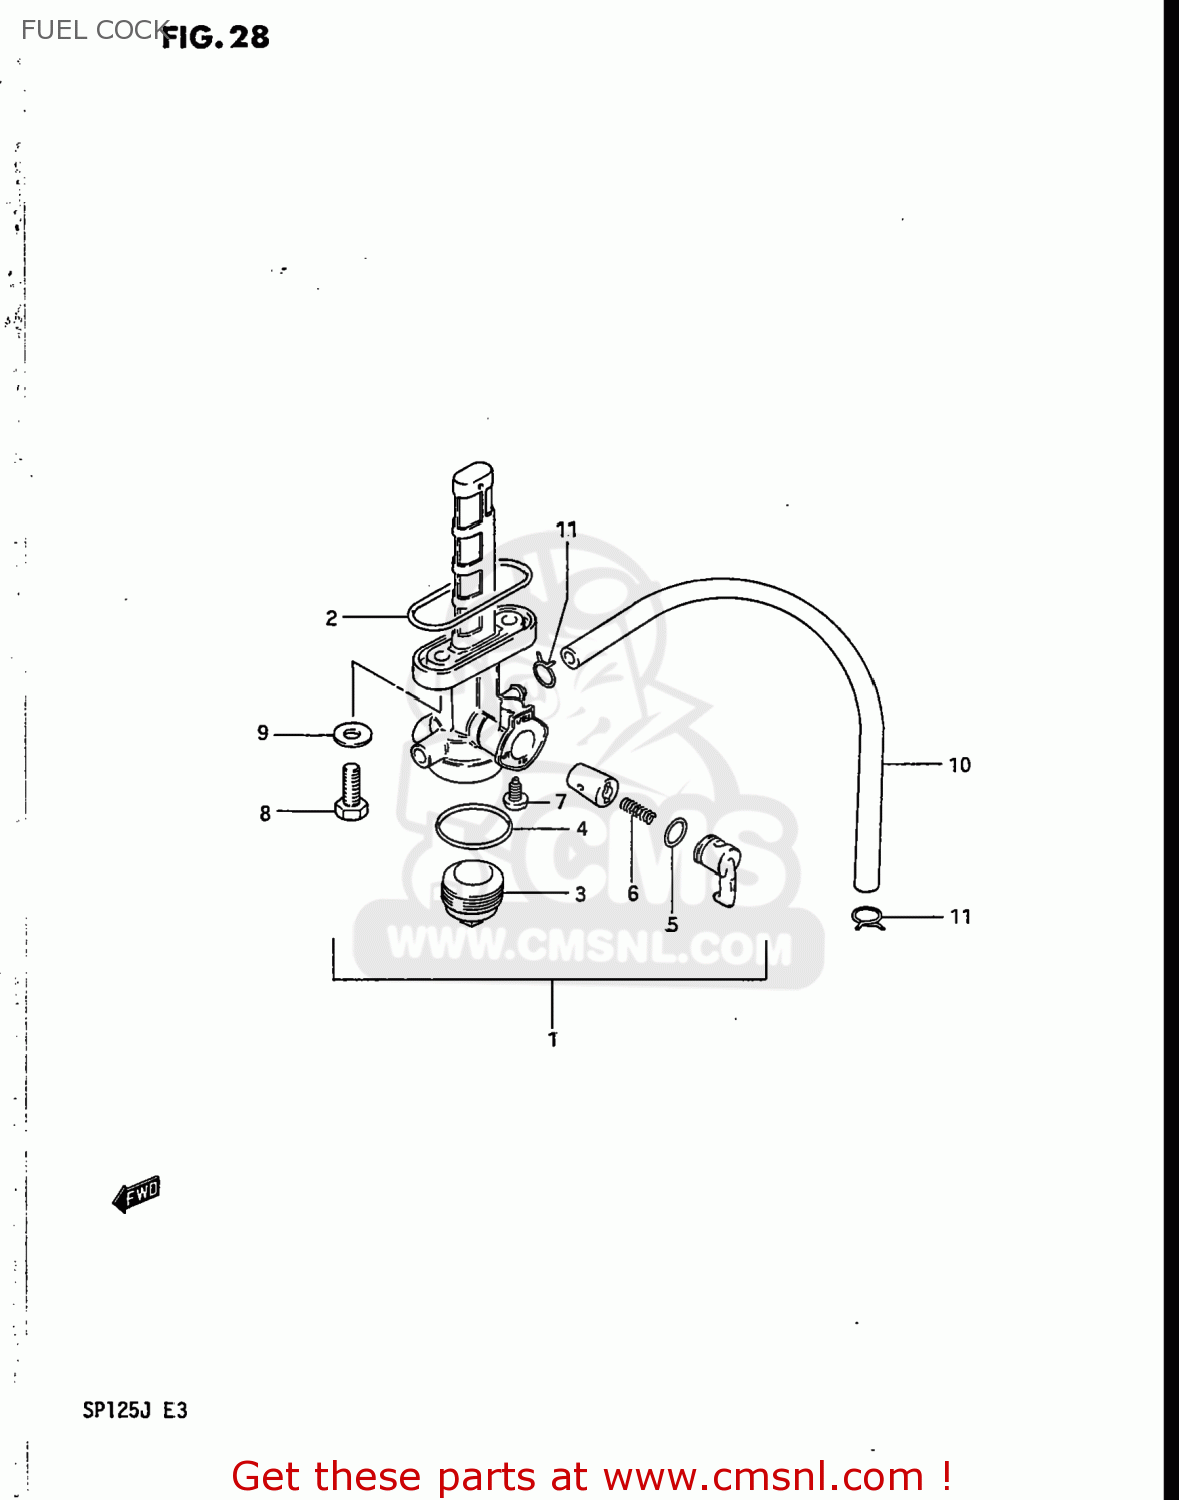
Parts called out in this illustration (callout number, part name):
1	COCK ASSEMBLY,FUEL
2	O RING,FUEL COCK
3	CUP,STRAINER
4	GASKET,FILTER (NAS)
5	O-RING
6	SPRING
7	SCREW
8	BOLT(6X20)
9	GASKET
10	HOSE
11	CLIP
